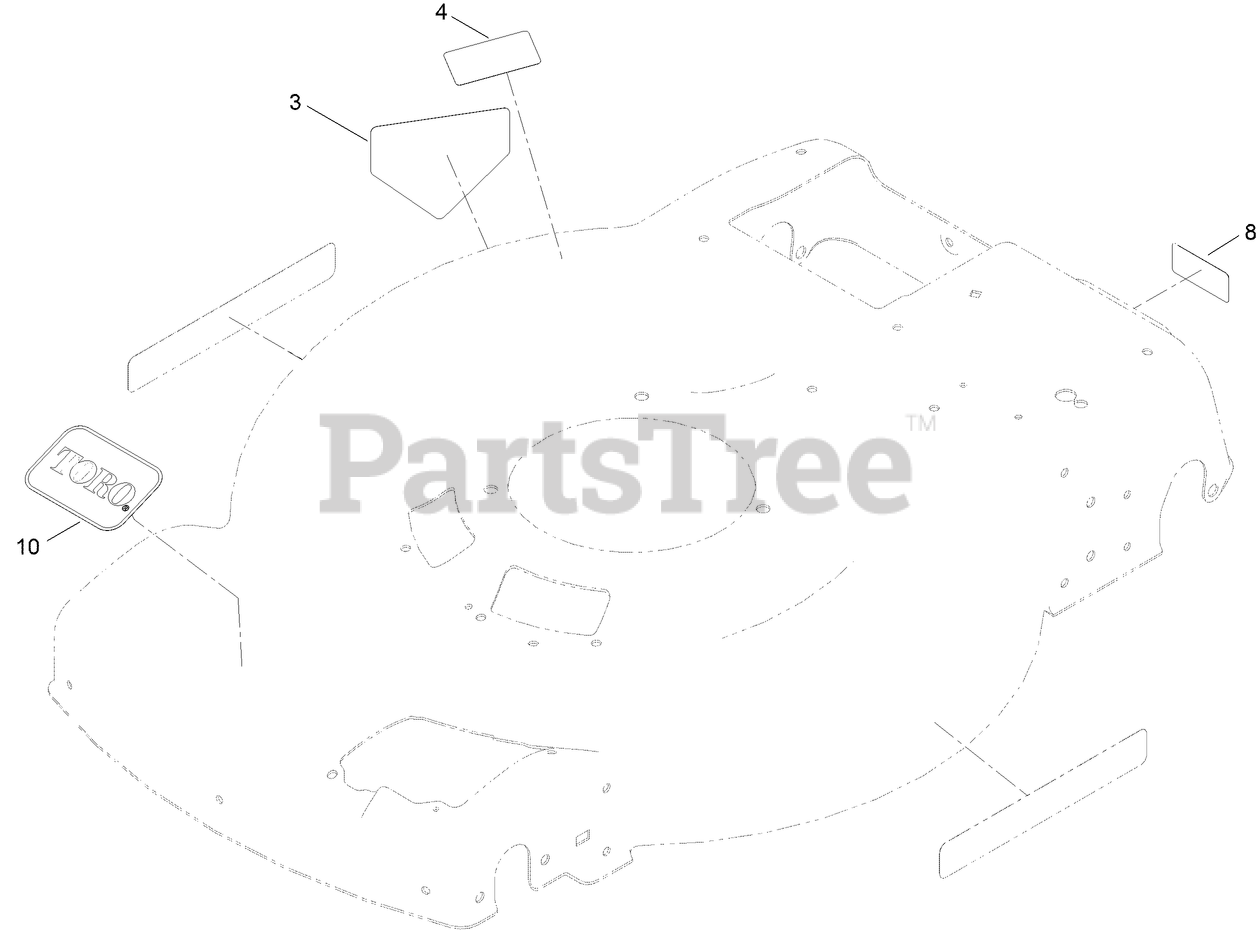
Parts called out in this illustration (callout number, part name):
3	DECAL-DANGER
4	DECAL-PLACEMENT, FOOT
8	DECAL-LOCATION, SERVICE DEALER
